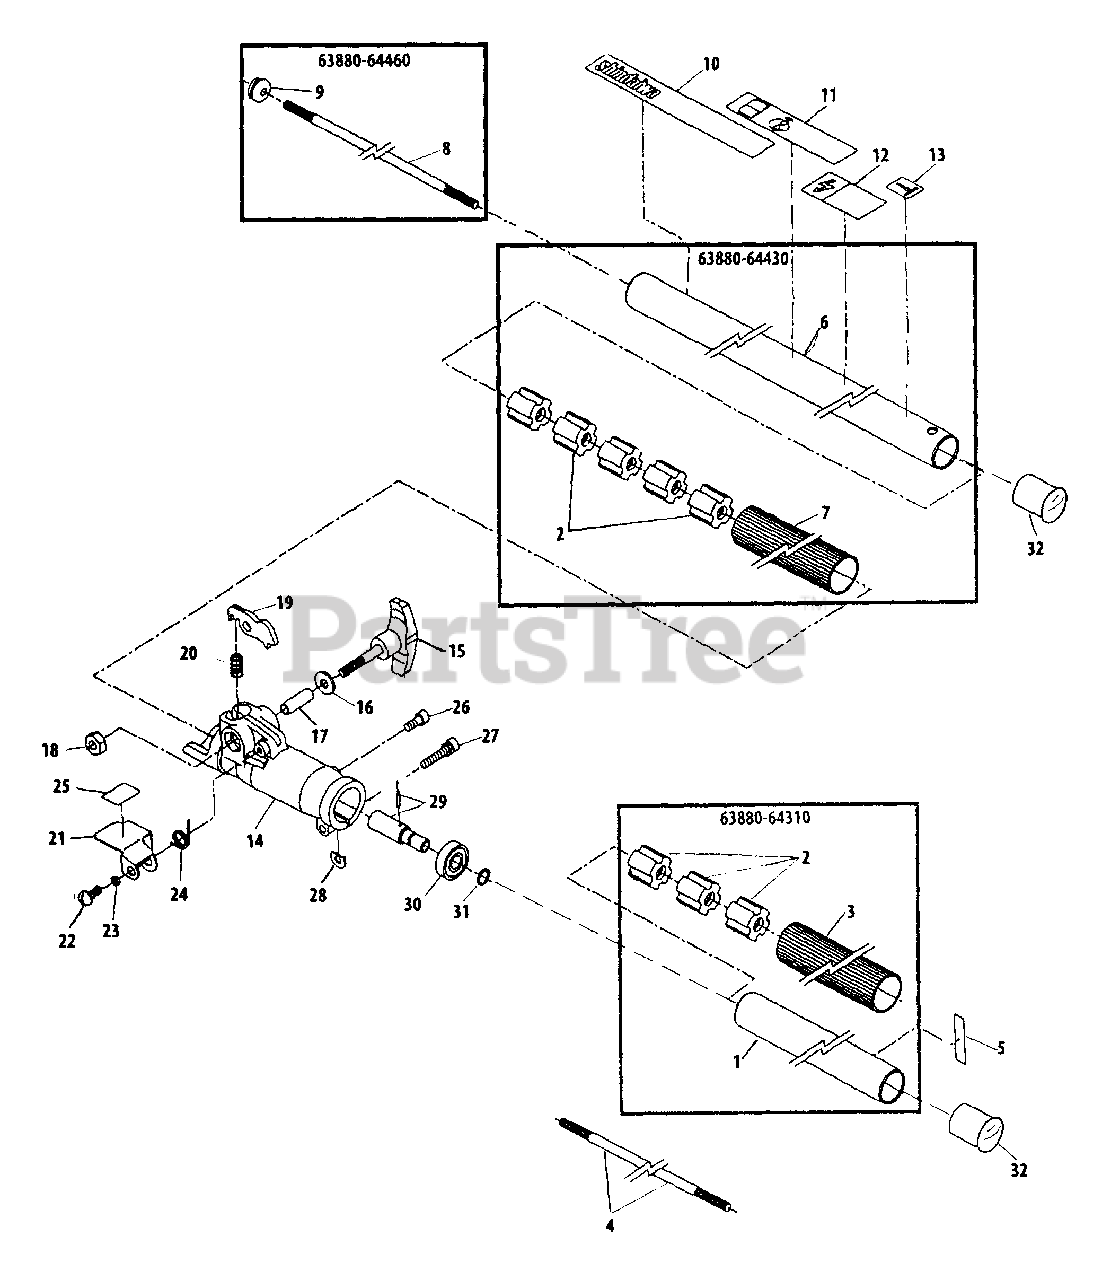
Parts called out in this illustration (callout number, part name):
1	PIPE, MAIN
2	BUSHING
4	MAINSHAFT
5	LABEL - ALIGNMENT
6	PIPE, MAIN
7	GRIP
8	PIPE, MAIN
9	GROMMET
10	LABEL - MODEL
11	LABEL, CAUTION
12	LABEL - CAUTION
13	LABEL, INSTRUCTION
14	HOUSING, COUPLER
15	KNOB, COUPLER SCREW
16	WASHER 6
17	COLLAR
18	NUT 6
19	LATCH
20	SPRING
21	PROTECTOR, LATCH
22	SCREW
23	WASHER 5
24	SPRING, TORSION
25	LABEL, LATCH INSTRUCTION
26	BOLT 5×12
27	BOLT M5×25
28	D-WASHER
29	SHAFT, COUPLER
30	BEARING, BALL 609ZZ
31	RING, SNAP
32	CAP
63880-64310	MAIN PIPE ASSY
63880-64430	MAIN PIPE ASSY
63880-64460	DRIVESHAFT ASSY
